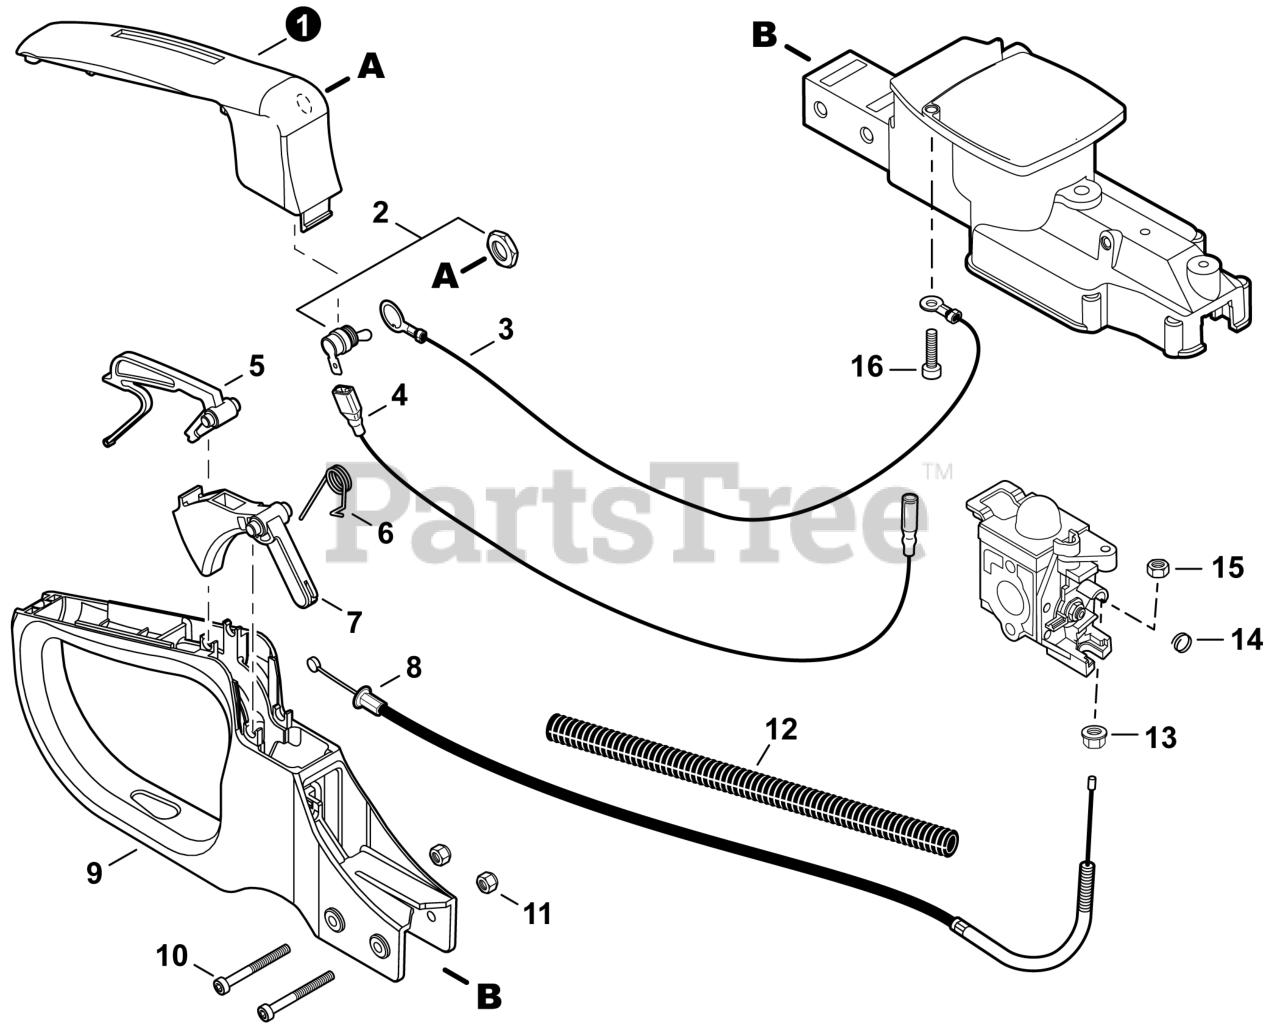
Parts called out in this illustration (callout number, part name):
1	COVER, HANDLE
2	SWITCH, ON-OFF
3	LEAD - GROUND L= 280
4	LEAD - IGNITION L= 260
5	LOCKOUT, THROTTLE
6	SPRING, TORSION
7	TRIGGER, THROTTLE
8	CABLE, THROTTLE
9	HANDLE, REAR
10	BOLT, TORX 5×45
11	NUT, FLANGE M5
12	TUBE, FLEXIBLE
13	NUT, FLANGE M6
16	BOLT, TORX 4×16
